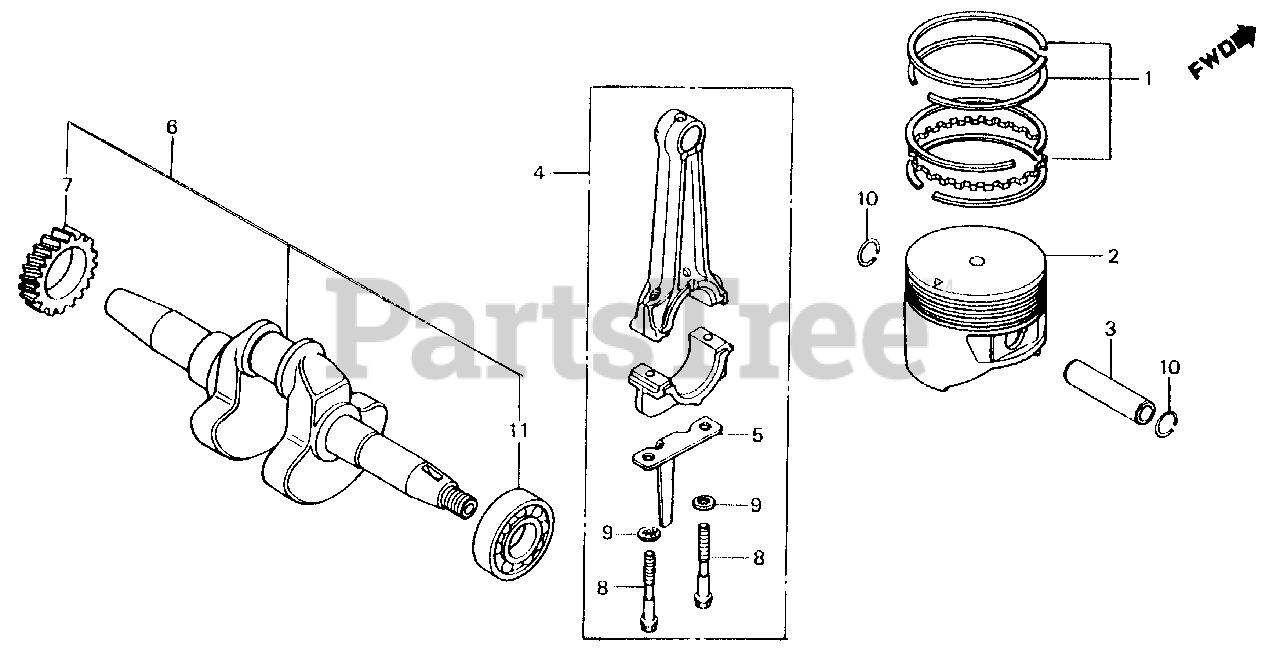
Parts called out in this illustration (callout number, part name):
1	RING SET, PISTON
1	RING SET, PISTON (OS 0.25)
1	RING SET, PISTON (OS 0.50)
1	RING SET, PISTON (0.75)
2	PISTON (STD)
2	PISTON (OS 0.25)
2	PISTON (OS 0.50)
2	PISTON (0.75)
3	PIN, PISTON
4	ROD ASSY., CONNECTING
5	DIPPER, CONNECTING ROD
6	CRANKSHAFT
7	GEAR, TIMING (NOT AVAILABLE)
8	BOLT, CONNECTING ROD (7MM)
9	WASHER, LOCK (7MM)
10	CLIP, PISTON PIN (16MM)
11	BEARING, RADIAL BALL (6205)
